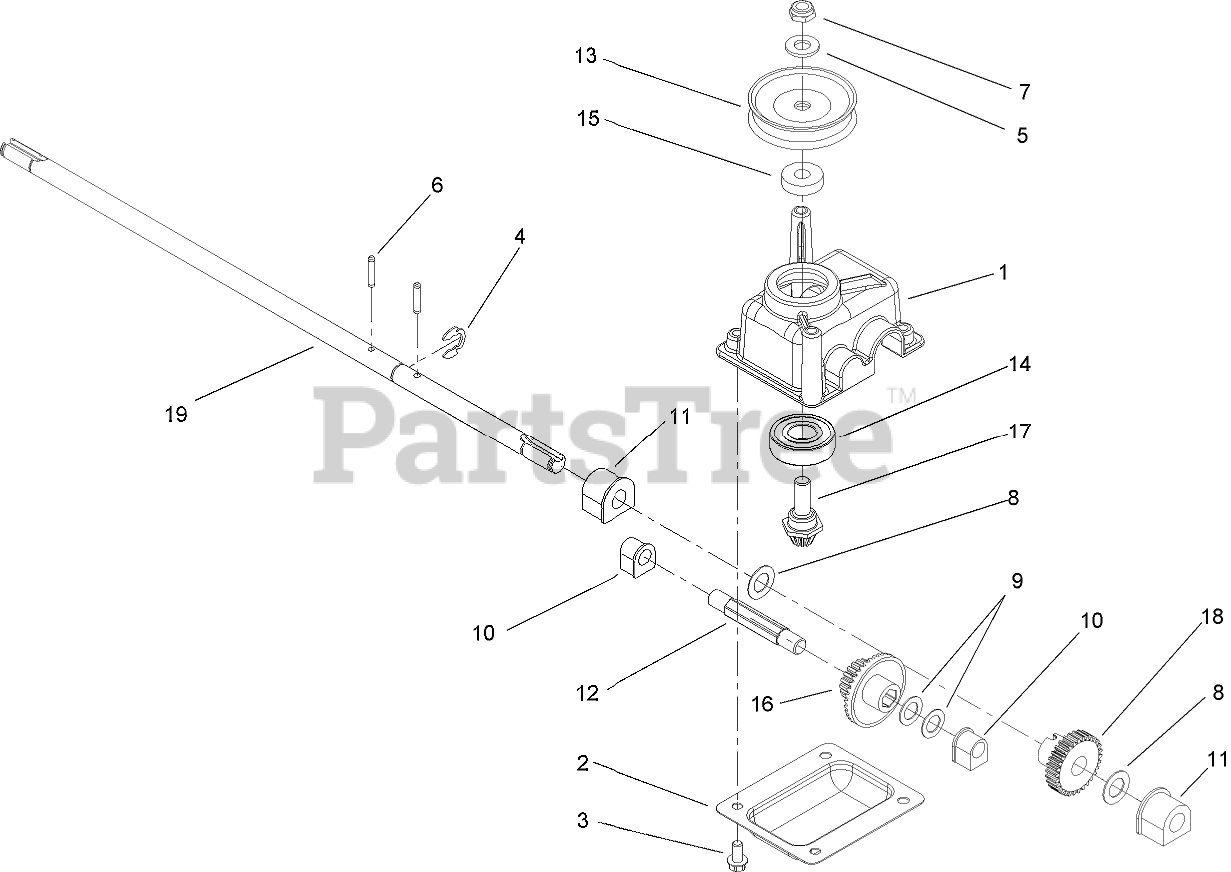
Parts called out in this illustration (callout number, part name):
1	CASE-GEAR
2	COVER-CASE, GEAR
3	SCREW-HWH
4	RING-RETAINING
5	WASHER-FLAT
6	PIN-GROOVE
7	NUT-HEX
8	WASHER-PLAIN
9	WASHER-THRUST
10	BUSHING
11	BUSHING
12	SHAFT-INTERMEDIATE
13	PULLEY-HALF
14	BEARING-BALL
15	SPACER
16	GEAR-19T SPUR, 37T BEVEL
17	GEAR-PINION, BEVEL
18	GEAR-30T
19	SHAFT-OUTPUT
